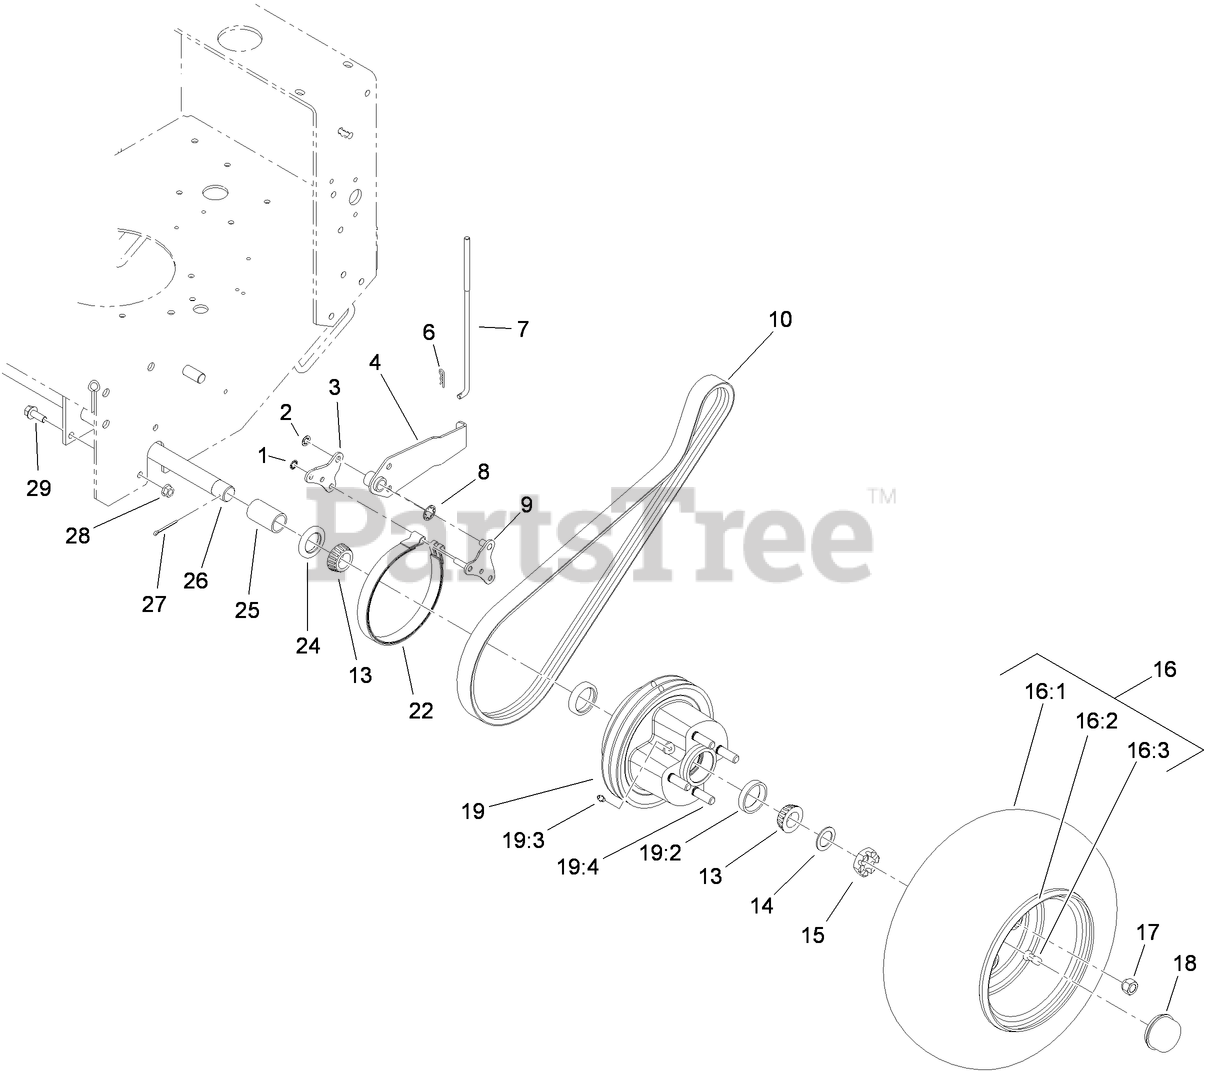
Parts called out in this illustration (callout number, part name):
1	RING-RETAINING
2	RING-RETAINING, EXTERNAL
3	PLATE-LINK, BRAKE
4	ARM-BRAKE
6	PIN-COTTER
7	ROD-BRAKE
8	RING-RETAINING
9	BRAKE LINK ASM
10	BELT-V, BANDED
13	BEARING-ROLLER, TAPERED
14	WASHER-SPACER
15	NUT-SHH
16	WHEEL AND TIRE ASM
16:3	STEM-VALVE
17	NUT-LUG
18	CAP-DUST
19	WHEEL HUB ASM
19:2	CUP-BEARING
19:3	FITTING-GREASE
19:4	STUD-TYPE, DRIVE
22	BAND-BRAKE
24	SEAL-GREASE
25	SPACER-WHEEL
27	PIN-COTTER
28	NUT-HF
29	SCREW-HHF
